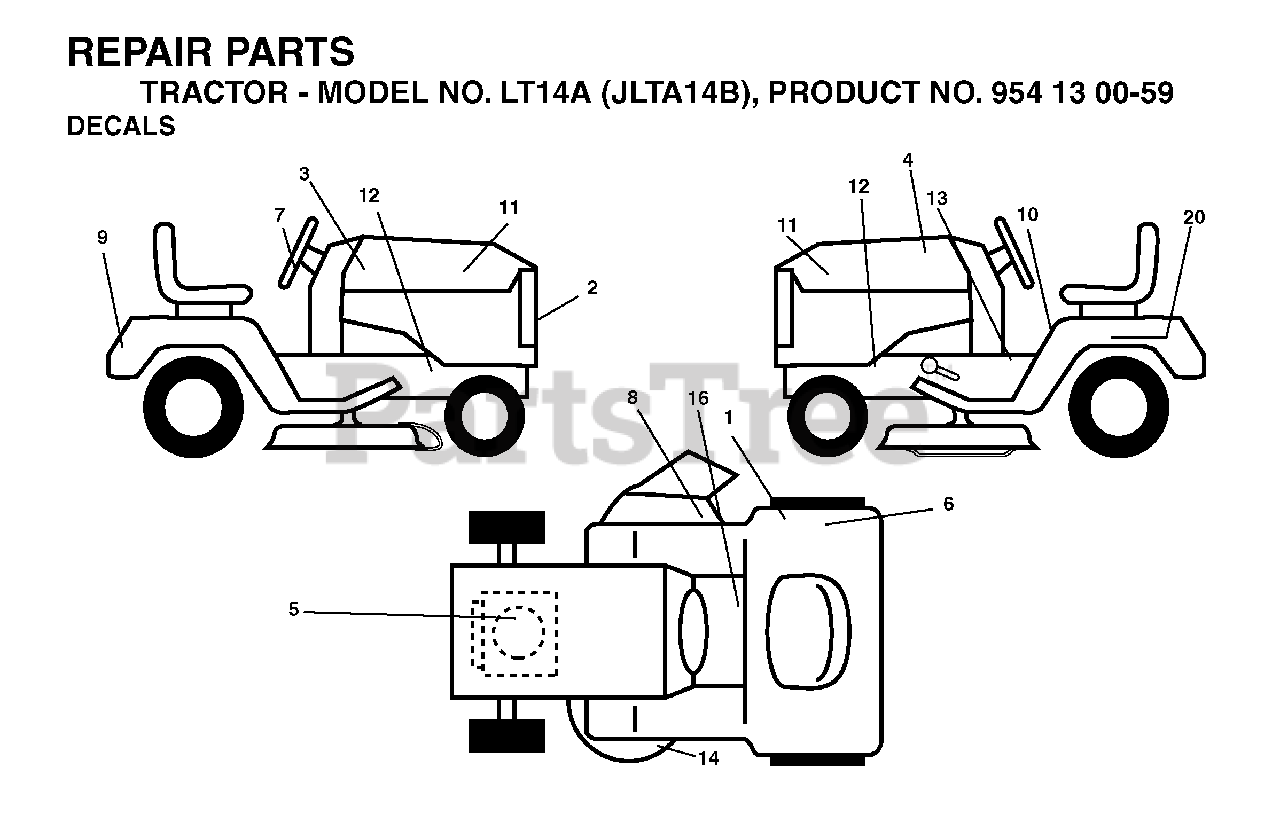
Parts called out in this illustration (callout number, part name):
8	DECAL.INTERNATIONL.CUTFINGER
10	DECAL READ OWNER'S MAN SYMS
14	DECAL V-BELT SCHEMATIC
16	DECAL PARK BRAKE
20	DECAL BTRY SYMBOLS
